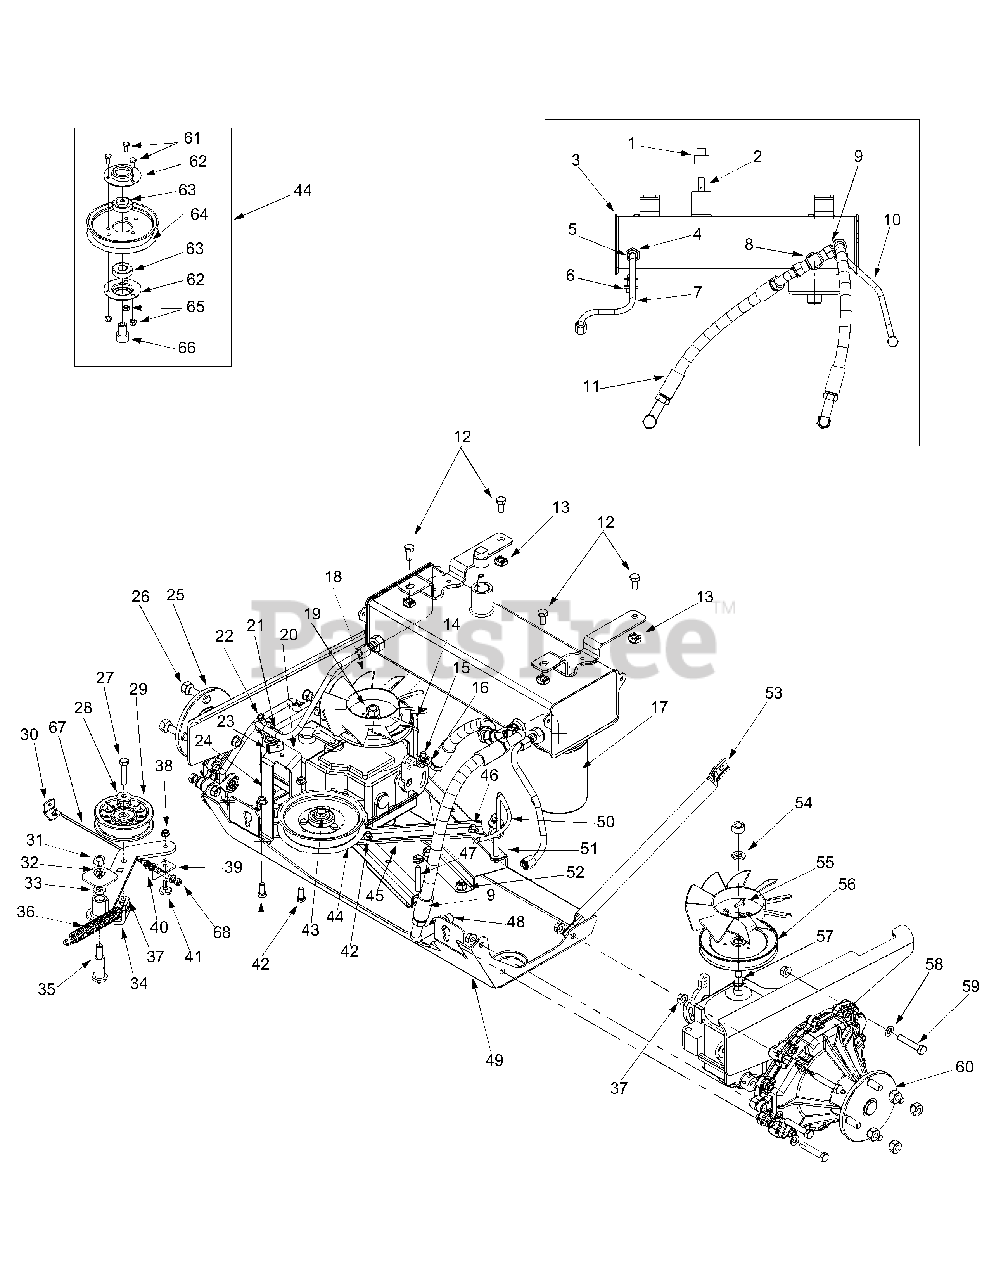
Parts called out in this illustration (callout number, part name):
2	Pipe Dipstick
5	Seal
7	Inlet Tube LH
9	Outlet Hose RH
10	Inlet Tube RH
11	Outlet Hose LH
12	Hex Cap Screw 3/8-16 x .75
13	Retainer Nut 3/8-16
14	Belt Retainer Rod RH
15	Hex Cap Screw 5/16-18 x 2.5
16	Flat Washer 5/16
17	Filter Element
18	Fan Blade
19	Hex Nut 1/2-20
20	Mounting Pulley Bracket
21	Roller Cable
22	Hex Shoulder Screw 1/4-28 x .375
23	Retainer Cable Bracket
24	Lock Nut 1/4-28
25	Complete Transmission Assembly LH
27	Hex Cap Screw 3/8-16 x 1.75
28	Flat Washer .385 ID x 1.0 OD
29	Flat Idler Pulley 3.5 OD
30	Mounting Bracket Cable
31	Hex Nut 7/16-14
32	Lock Washer 7/16
33	Flat Washer .469 ID x .875 OD
36	Extension Spring 6.12 Lg
37	Flange Lock Nut 3/8-16
38	Hex Nut 1/4-28
39	Lock Washer 1/4
40	Flat Washer .283 ID x .75 OD
41	Hex Cap Screw 1/4-28 x 1.25
42	Hex Cap Screw 5/16-18 x .75
43	Hex Cap Screw 3/8-16 x 2.25
44	Idler Pulley Assembly 5.0"
47	Hex Cap Screw 5/16-18 x 2.0
48	Connection Fitting 1/2 x 3/8
55	Hex Washer Screw #12-24 x .625
56	Transmission Pulley
59	Hex Cap Screw 3/8-16 x 2.0
60	Complete Tranmission Assembly RH
61	Hex Cap Screw 1/4-20 x .62
63	Ball Bearing
64	Idler Pulley 5.0"
65	Hex Lock Nut 1/4-20
66	Idler Spacer
67	Declutching Cable
68	Jam Nut 5/16-18
